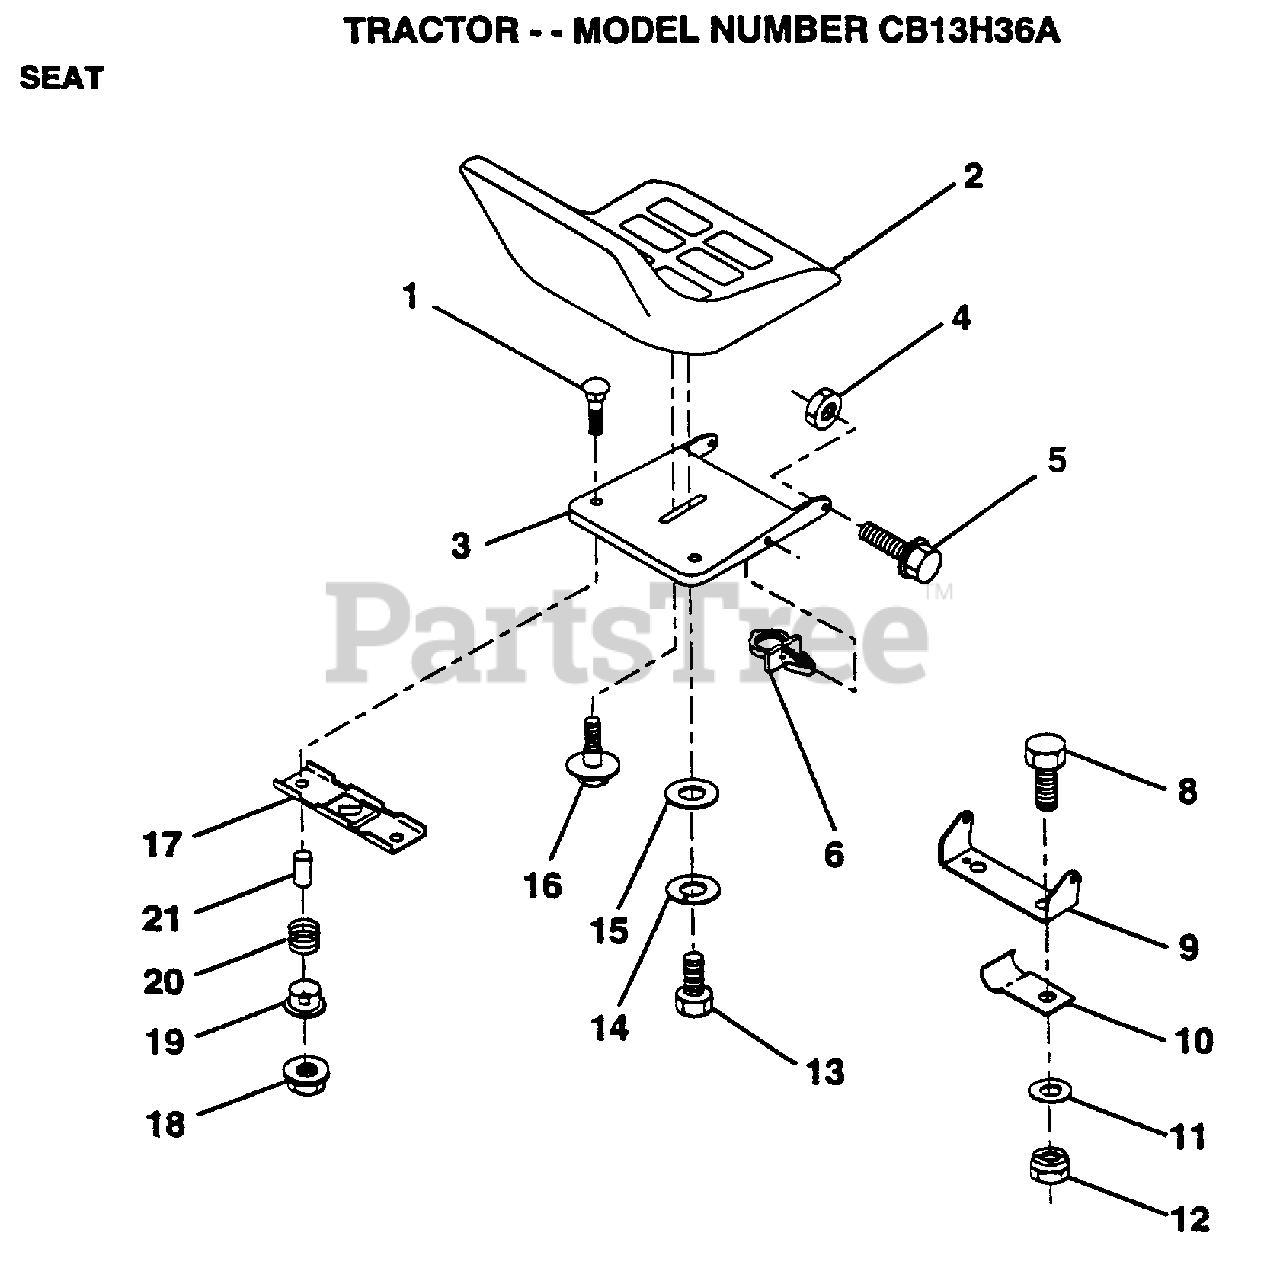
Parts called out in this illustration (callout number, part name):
4	NUT
5	BOLT.SHLD.5/16-18
6	CLIP.PUSH-IN.HING
8	BOLT
9	BRACKET PVT SEAT
10	"CLIP,INSULATOR"
11	WASHER
12	NUT
13	BOLT
14	LOCKWASHER
15	WASHER
16	"BOLT,SHOULDER"
17	BRKT SWITCH
19	BUSHING
20	SPRING
21	SPLIT SPACER
